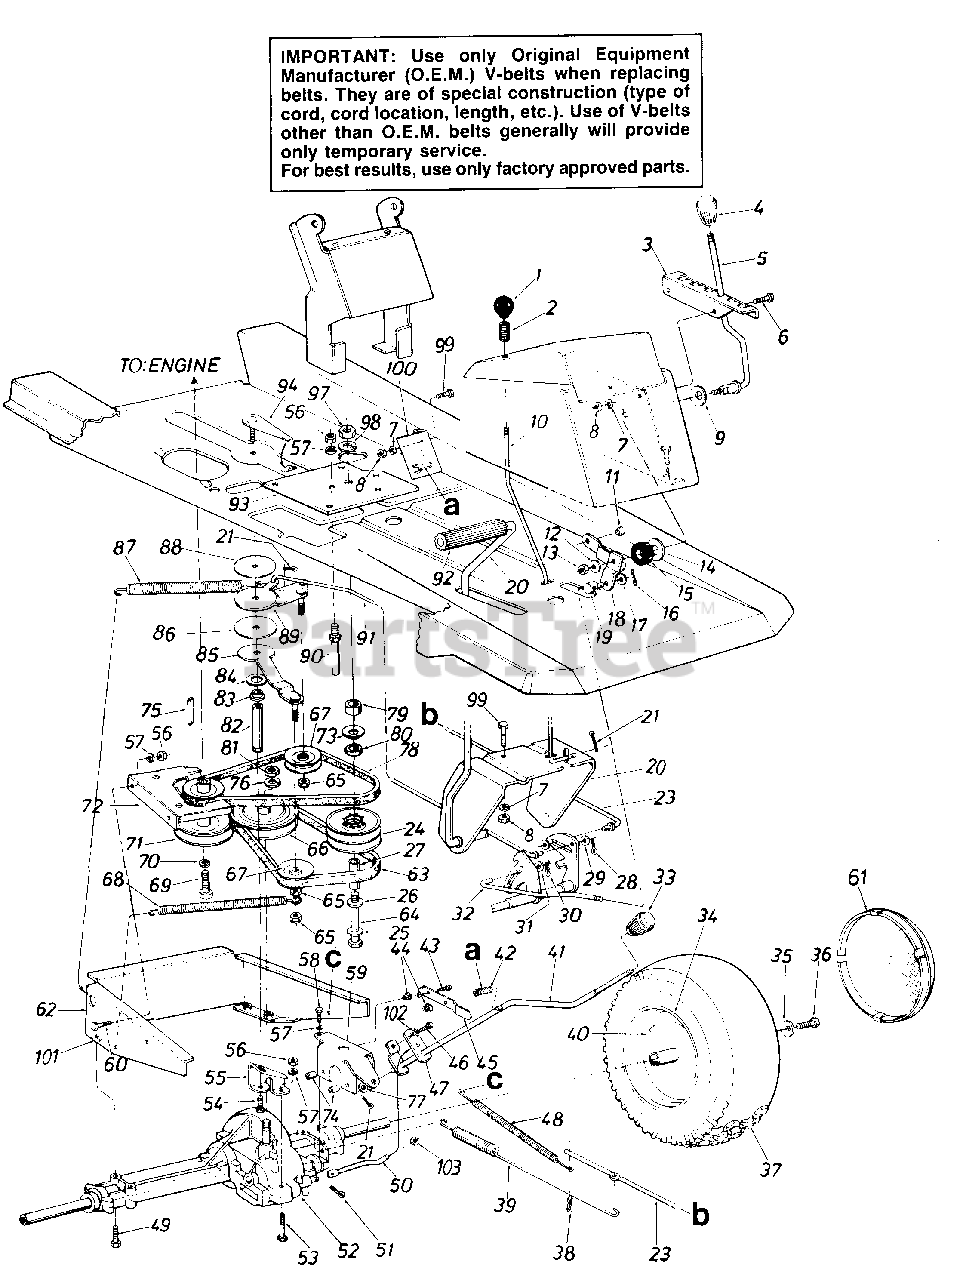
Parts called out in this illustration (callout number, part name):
1	Ball Knob 1/4-20 Thd. 1.25
2	Compression Spring
5	Speed Control Lever
6	Truss Mach. Scr. 5/16-18 x .75" Lg.
7	L-Wash. 5/16" I.D.
8	Hex Nut 5/16-18 Thd.*
9	Bell-Wash. 345" I.D. x .88"
10	Brake Locking Rod
12	Bell-Wash. .345" I.D. x .08"
13	Hex Cent. L-Nut 5/16-18 Thd.
14	Fl-Wash. .50" I.D. x 1.5" O.D.
15	Rubber Washer
16	Intern. Cotter Pin 1/2" Dia.
17	Fl-Wash. .34" I.D. x .68" O.D.
18	Speed Control Lever Brkt. Ass'y.
19	Ferrule-Engagement
20	Clutch/Brake Pedal Ass'y.
21	Cotter Pin 3/32" Dia. x .75"*
24	Variable Speed Pulley Ass'y.
25	Fl-Wash. .4" I.D. x 1.25" O.D.
26	Thrust Brg. 1.25" O.D. x .56" I .D.
27	Spacer Sleeve 2.71"
28	Cotter Pin 1/8" Dia. x 1.25"*
29	Fl-Wash. .34" I.D. x .60" O.D.
30	Intern. Cot-Pin 5/16" Dia.
31	Fl-Wash. .34" I.D. x .60" O.D.
32	Speed Control Rod
33	Shift Knob
35	Bell-Wash. .345" I.D. x .88"
36	Hex L-Bolt 5/16-24 x .75" Lg.
38	Cotter Pin 1/8" Dia. x 1.25"*
39	Extension Spring 17.0" Lg.
40	Air Valve
43	C Sink ABS-Tap Scr. #8 x .50" Lg.
44	Push-in Nut #10
45	Spring Switch
46	Hex Bolt 1/4-20 x .50" Lg.
47	Shift Lever Adjusting Link
48	Ext. Spring 8-1/4" Lg.
49	Hex Bolt 5/16-18 x 2.5" Lg.
51	Intern. Cotter Pin
52	Transaxle
53	Hex Bolt 1/4-20 x 1.75" Lg.*
54	Hex Bolt 3/8-24 x .75" Lg.*
57	L-Wash. 1/4" I.D.*
58	Self-Tap Mach. Scr. Type "C" 1/4-20 x 1.37" Lg.
59	Shift Lever Support Brkt.
60	Hex Bolt 1/4-20 x 1.00" Lg.*
61	Chrome Hub Cap
64	Hex Bolt 3/8-16 x 4.5" Lg.
65	Hex Ins. L-Nut 3/8-24 Thd.
66	5/8 V-Pulley .500" I.D. x 6"
67	V-Belt Idler .38" I.D. x 3.06"
68	Ext. Spring .50" O.D. x 6.37"
69	Hex Bolt 7/16-20 x 1.00" Lg.
70	L-Wash. 7/16" I.D.
71	Engine Pulley .500" O.D. & 3.56" O.D.
72	Upper Eng. Belt Guard
73	Bell-Wash. .4" I.D. x 1.12" O.D.
74	Spacer .256" I.D. x .50" O.D.
75	Sq.-Key 1/4" x 2.00" Lg.
76	L-Wash. 1/2" I.D.*
77	Fl-Wash. .469" I.D. x .88" O.D.
78	V-Belt
79	Spacer 1.00" x .380" O.D.
80	Thrust Wash. .56" I.D. x 1.25" O.D.
81	Hex Nut 1/2-13 Thd.*
83	Flange Bearing .378
84	Fl-Wash. .640" I.D. x 1.24"
85	Idler Bracket Ass'y.
86	Thrust Wash. .635" I.D.
87	Extension Spring 7.58" Lg.
88	Thrust Wash. .385" I.D.
89	Idler Bracket Ass'y. For Clutch
90	Belt Guard Pin 1/4" Dia.
92	Foot Pad
93	Mtg. Brkt. Variable Pulley
98	L-Wash. 3/8 Heavy Duty
99	Hex Bolt 5/16-18 x .75" Lg.*
100	Shift Lever Spring Brkt.
101	Hex Sems Nut 5/16-18 Thd.
102	Bell-Wash. .265" I.D. x .75" O.D.
103	Push On Retaining Ring
